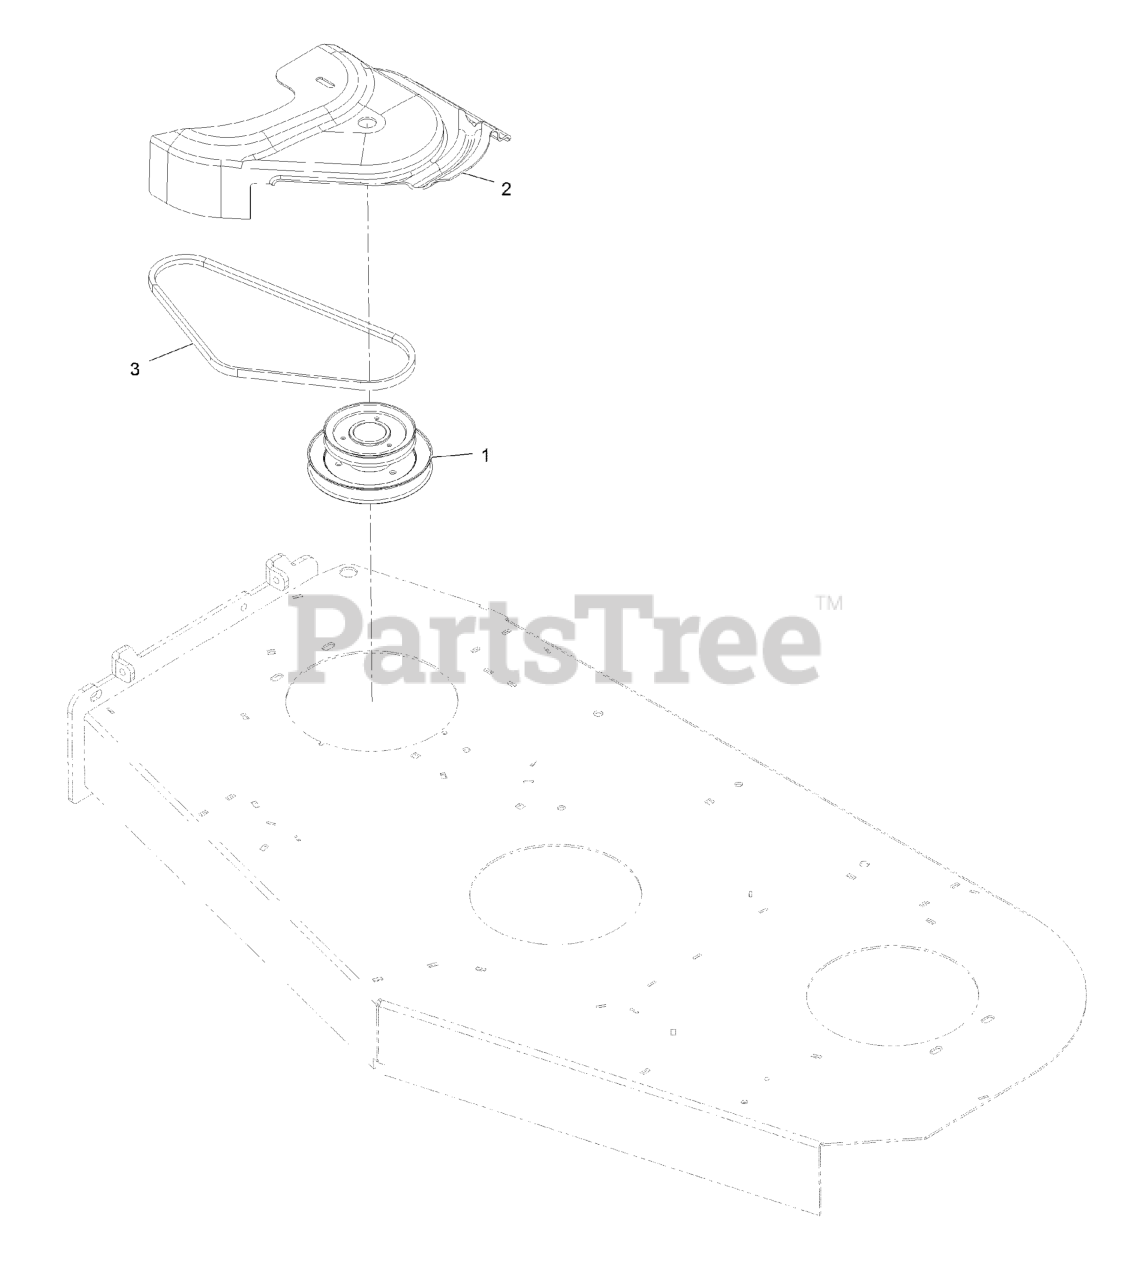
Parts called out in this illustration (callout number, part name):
1	JACKSHAFT, UV DRIVE 604 S
2	COVER,BELT DUV 60
3	BELT, BLOWER DRIVE 60
